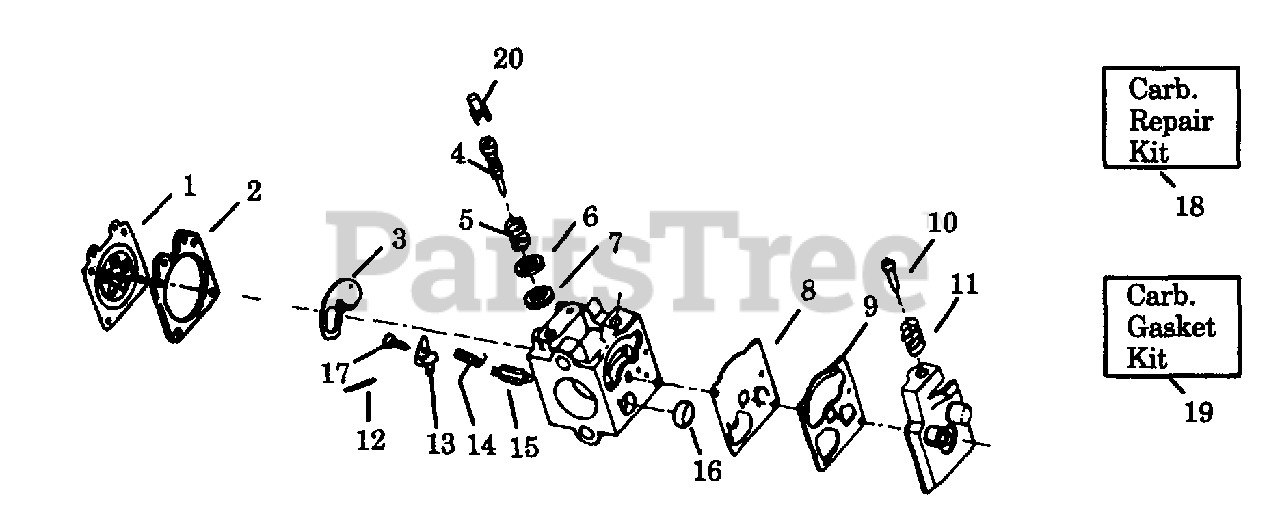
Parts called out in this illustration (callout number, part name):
1	Metering Diaphragm
2	Metering Diaphragm Gasket
3	Circuit Plate Gasket
4	Mixture Needle Type I (WA-207/207A)
4	Mixture Needle Type II (WA-219)
5	Mixture Needle Spring Type I (WA-207/207A)
5	Mixture Needle Spring Type II (WA-219)
6	Mixture Needle Washer
7	"O" Ring Mixture
8	Fuel Pump Diaphragm
9	Fuel Pump Gasket
10	Idle Speed Screw
11	Idle Speed Spring
12	Metering Lever Pin
13	Metering Lever
14	Metering Lever Spring
15	Inlet Needle Valve
16	Fuel Inlet Screen
17	Metering Lever Pin Screw
18	Carb. Kwik Repair Kit
19	Carb. Gasket/Diaphragm Kit
20	Limiter Cap
